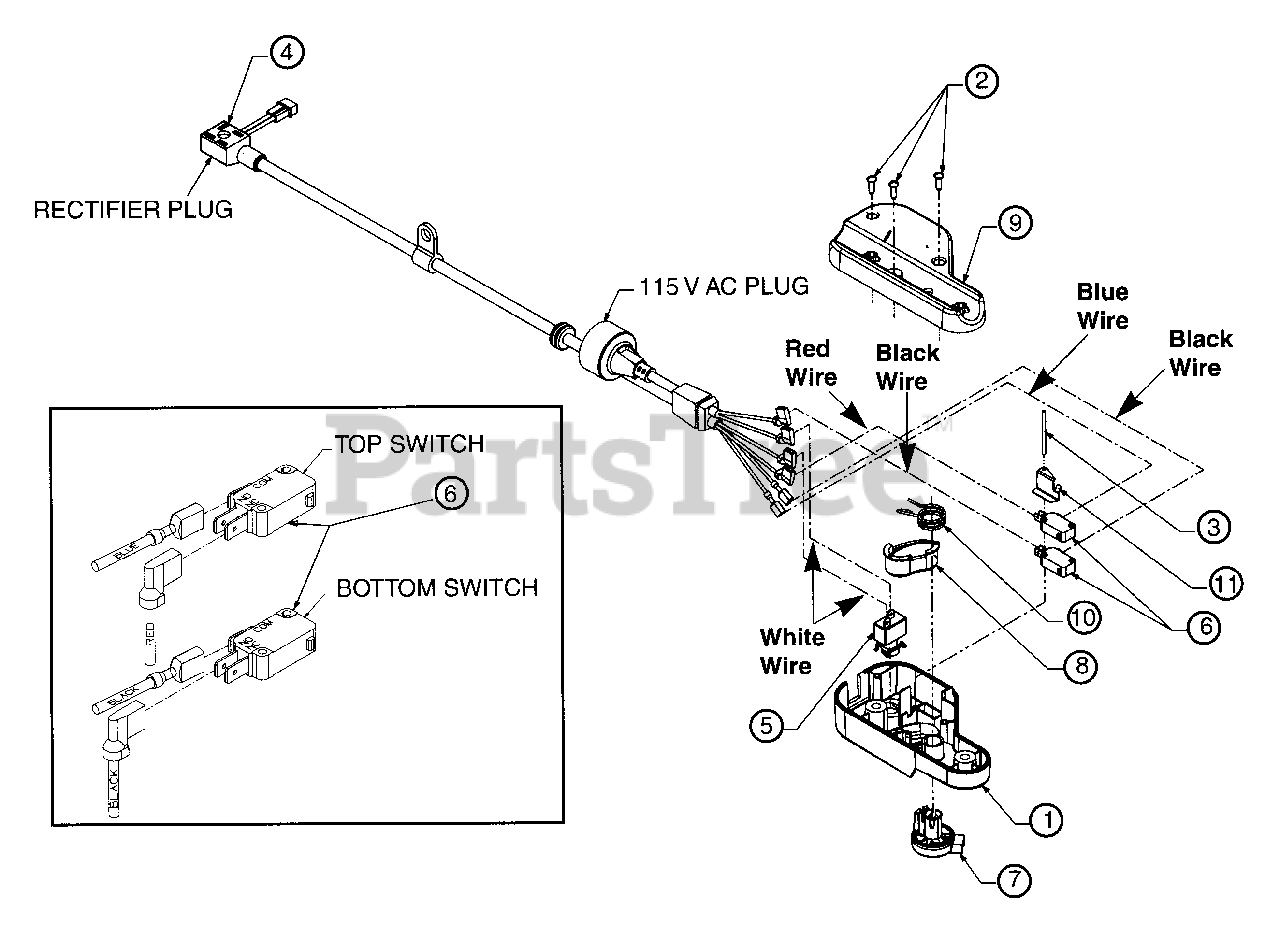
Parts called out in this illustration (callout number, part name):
1	Switch Housing Assembly
2	Drive screw #8 x 1/2 Lg.
3	Pivot
4	Cord, 115 Volt w/Plug
5	Circuit Breaker
6	Switch, Micro 20 Amp.
7	Clip, Bail Lock
8	Button, Bail Lock
9	Switch Housing - R.H.
10	Torsion Spring
11	Actuator Arm
